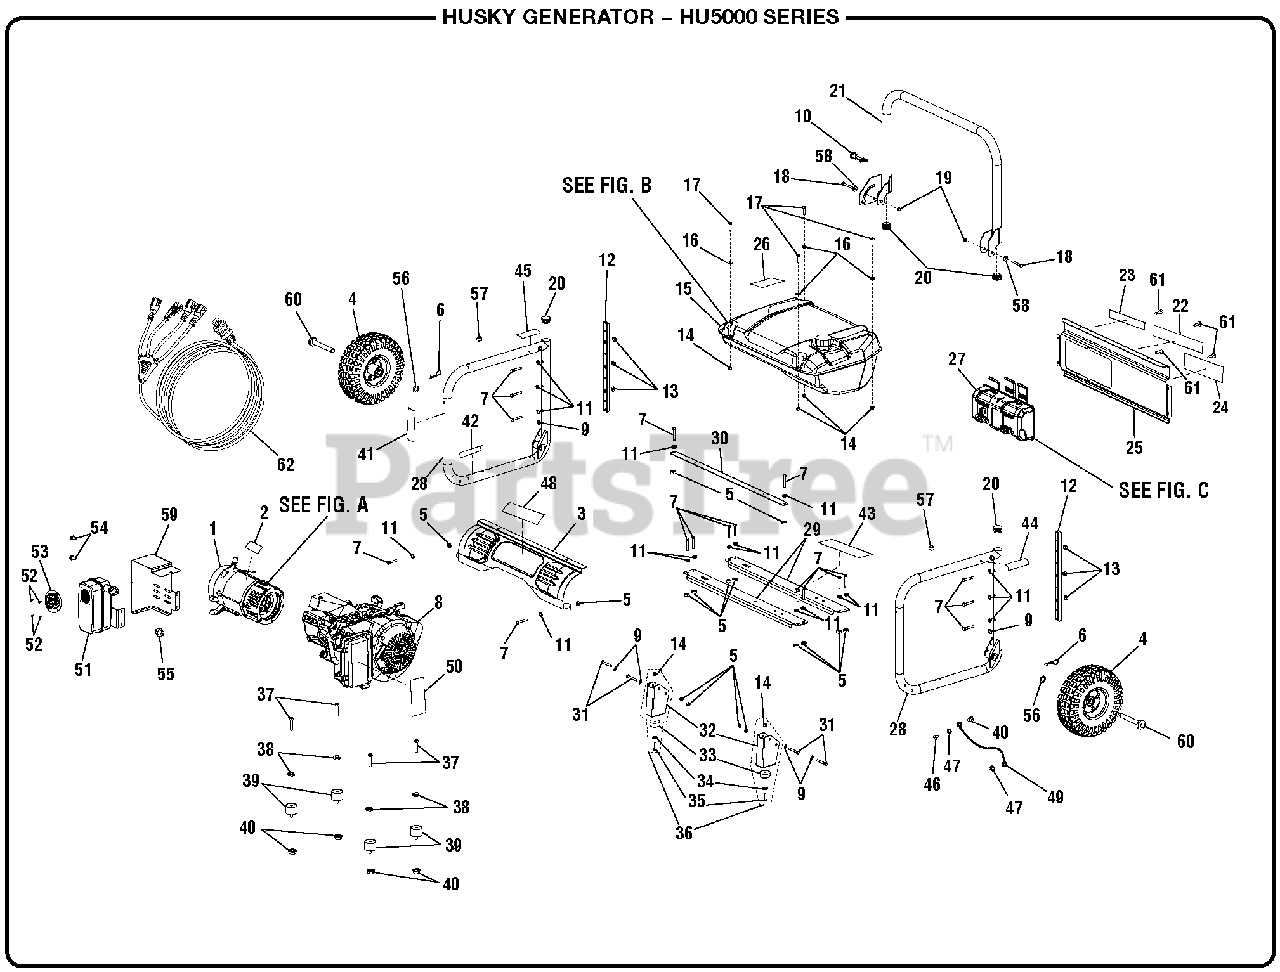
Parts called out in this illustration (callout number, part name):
1	Generator Head w/AVR
2	Data Label
3	Back Panel Assembly
5	Lock Nut (1/4-20)
6	Hitch Pin
7	Bolt (1/4-20 x 42.5 mm, Torx)
8	Engine (EX30 Subaru)
9	Washer (1/4)
10	Handle Release Pin Assembly
11	Lock Washer (M6)
12	Frame Slide Rails
13	Hex Nut (1/4-20)
14	Lock Nut (1/4-20)
15	Fuel Tank Assembly
16	Washer (1/4 in.)
17	Bolt (1/4-20 x 1 in., Hex Hd.)
18	Bolt (5/16 x 18, Hex Hd.)
19	Lock Nut (5/16 x 18)
21	Handle Assembly
22	Danger Label
23	Ground Warning Label
24	Logo Label
25	Front Panel
26	CPSC Label
27	Control Box (Front and Rear Assembly)
28	Frame Tube Assembly
29	Frame Cross Brace
30	Back Frame Bracket
31	Bolt (1/4-20 x 2 in., T30 Torx Hd.)
34	Washer (1/4)
35	Bolt (1/4-20 x 1 in., Hex Hd.)
36	Foot Assembly
37	Bolt (5/16-18 x 1-1/2 in.)
38	Lock Washer (5/16)
39	Isolator (Generator)
40	Flange Nut (5/16-18, Hex Hd.)
41	Hot Surface Label
42	Combustion Label
43	Engine Lubricant Label
44	Fire Danger Label
45	Pin Release Label
46	Bolt (5/16-18 x 3/4 in.)
47	Star Washer (5/16 in.)
48	Back Panel Logo Label
49	Ground Wire Assembly
50	Starting Instruction Label
52	Spark Arrestor Screw
53	Spark Arrestor
54	Bolt (5/16-24 x 5/8 in.)
55	Muffler Gasket
56	Washer (5/8 x 1 x 5/8 in.)
57	Rubber Handle Bumper
58	Washer (5/16)
59	Back Muffler Cover
61	Screw (6-20 x 3/8 in., Pan Hd.)
62	Extension Cord
